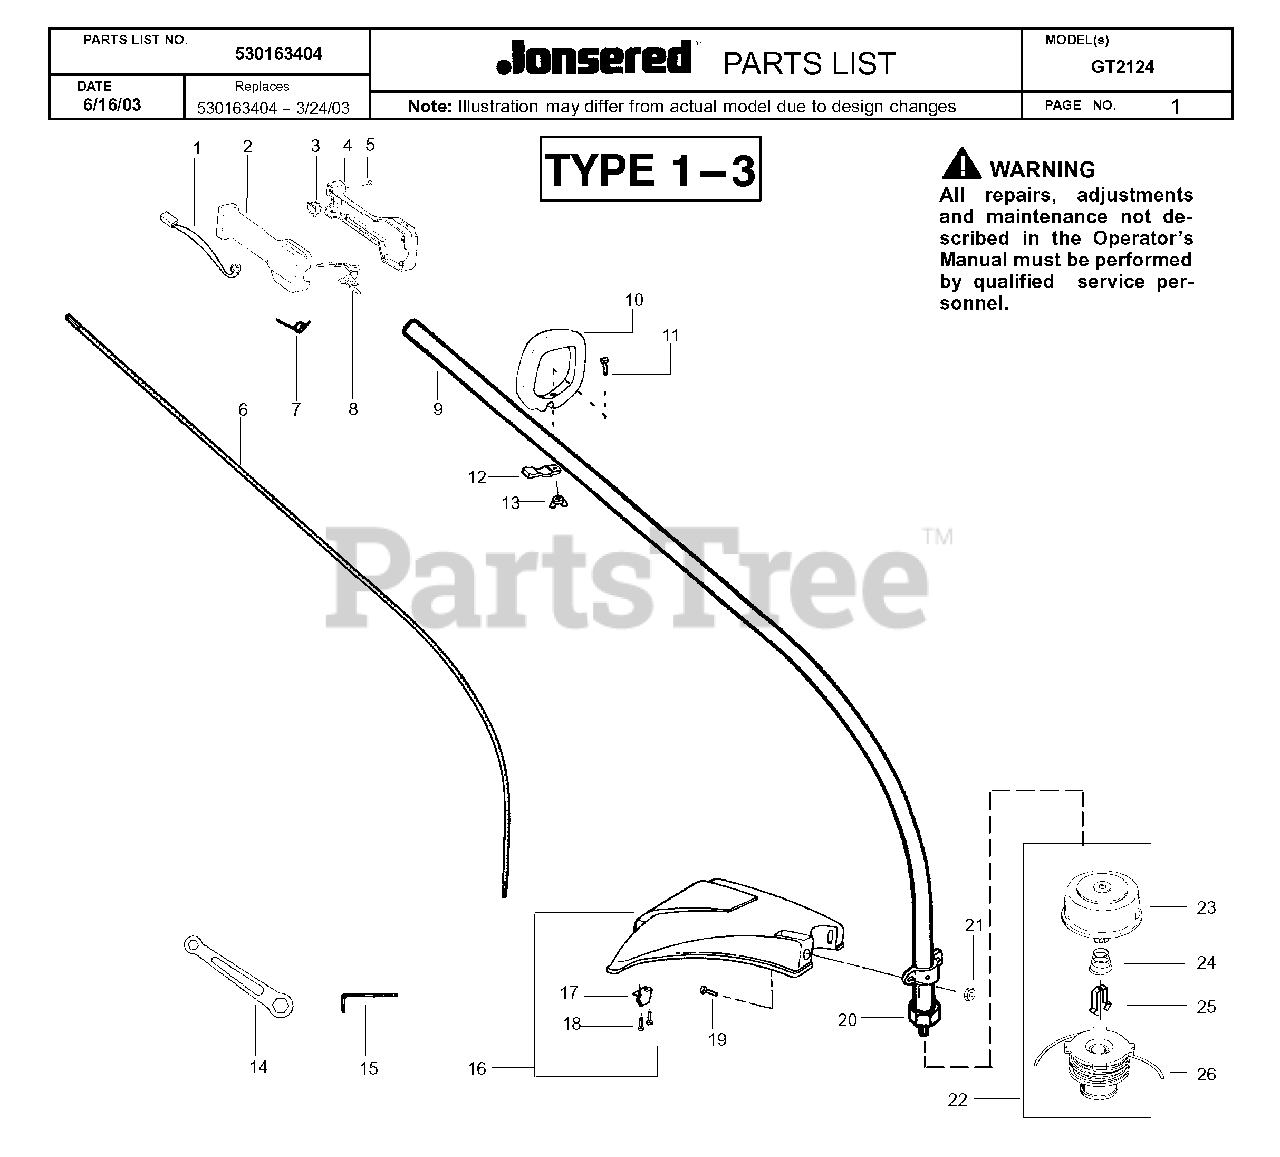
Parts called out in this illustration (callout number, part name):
5	SCREW-10-14 X 13/16 (PL
6	SHAFT-FLEX (48")
7	SPRING-LEVER RETURN
8	THROTTLE TRIGGER
10	HANDLE ASSY
11	BOLT, TYPE 2
13	NUT - HANDLE/SHIELD
15	HEX WRENCH 5/32
17	LINE CUTTER
19	BOLT, TYPE 2
23	KIT ASSY HUB W/ARBOR
